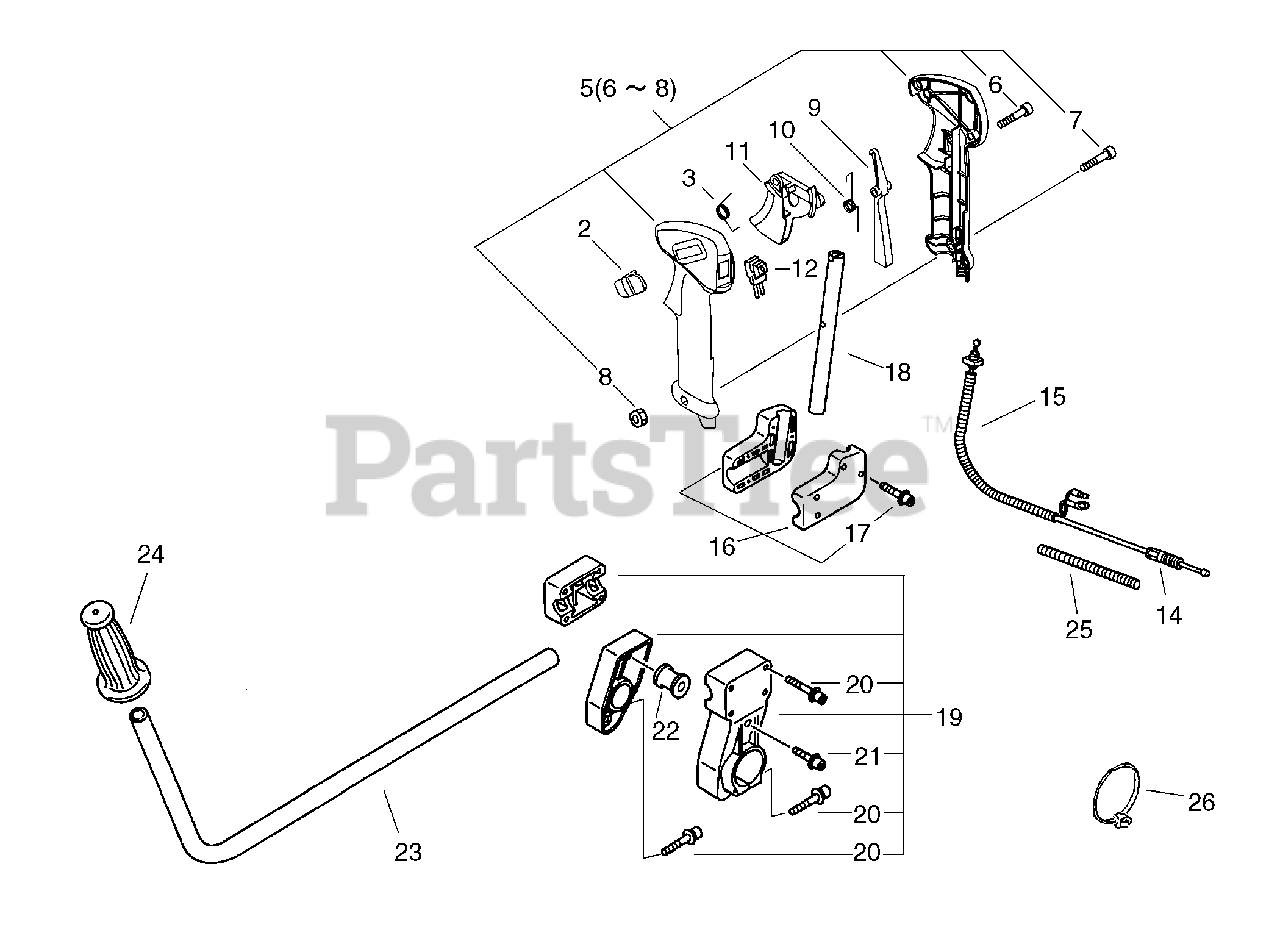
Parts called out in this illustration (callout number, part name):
2	LATCH, THROTTLE
3	SPRING, TORSION
5	CONTROL HANDLE ASSY
6	SCREW 4×16
7	SCREW 5×30
8	NUT M5
9	LOCKOUT, THROTTLE
10	SPRING, TORSION
11	TRIGGER, THROTTLE
12	SWITCH, ON-OFF
14	CABLE, THROTTLE
16	BRACKET ASSY, HANDLE
17	BOLT 5×25
18	HANDLE, REAR
19	BRACKET ASSY, HANDLE
21	BOLT 5×14
23	HANDLE, FRONT
26	BAND
